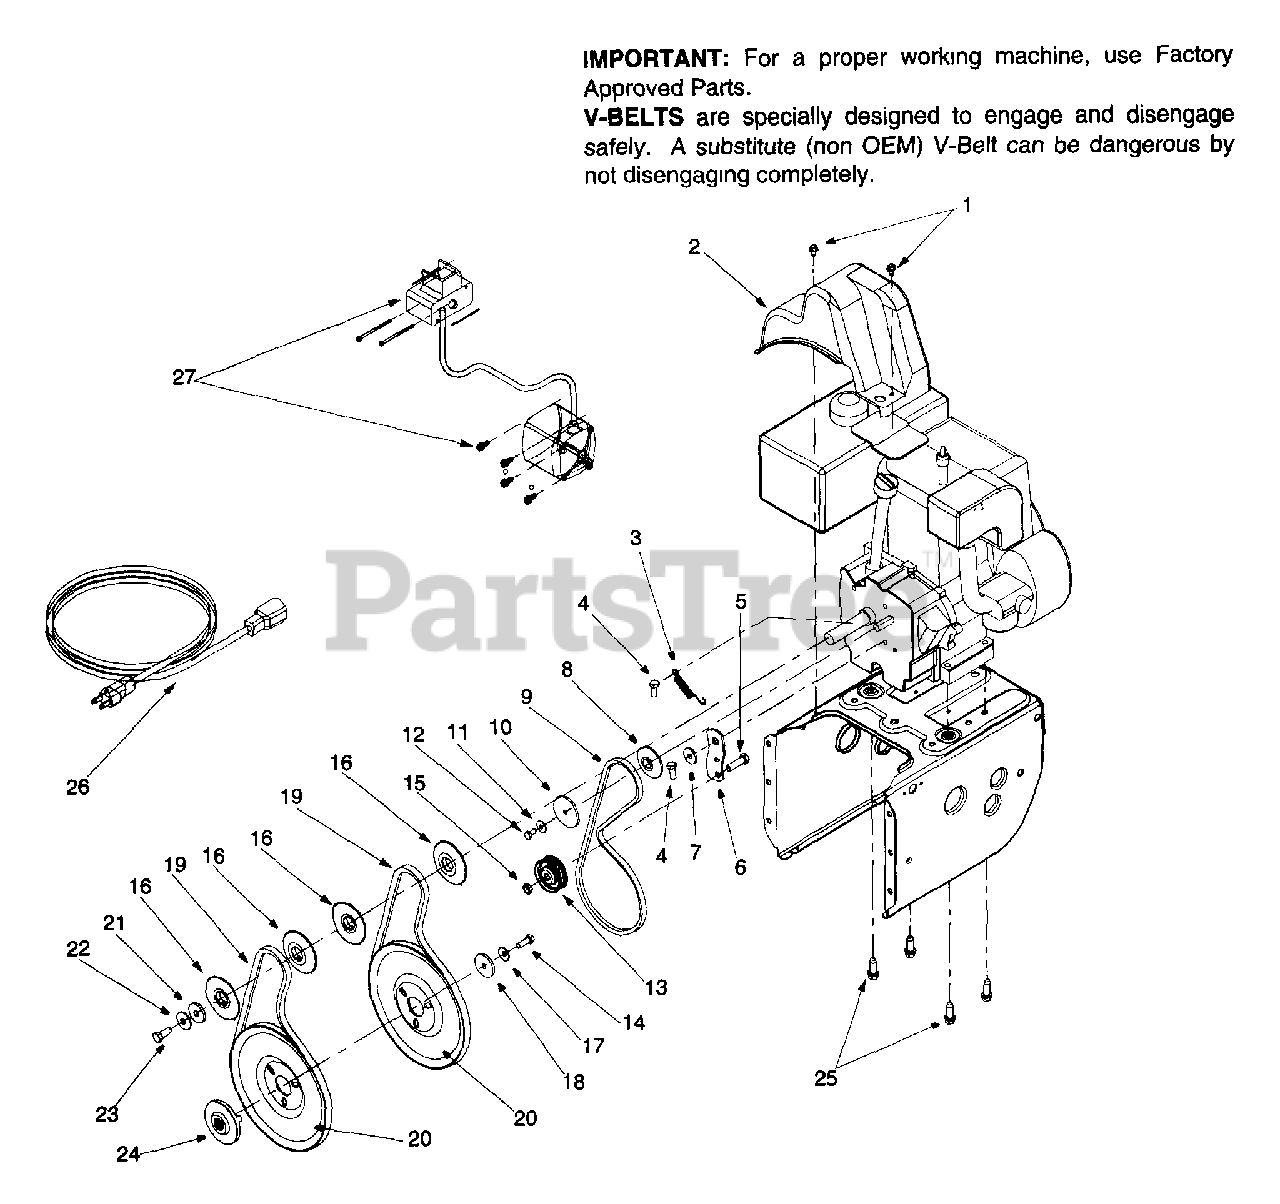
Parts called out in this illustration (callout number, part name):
1	Hex Washer Screw 1/4-20 x .50
2	Belt Cover
3	Extension Spring
4	Hex Screw 5/16-24 x .75
5	Hex Cap Screw 3/8-16 x 1.25
8	Pulley Half
9	V-Belt
10	Pulley Half
11	Bell Washer
12	Hex Cap Screw 1/4-28 x .50
13	Flat Idler
14	Lock Hex Cap Screw 5/16-24
15	Lock Jam Nut 3/8-16
16	Pulley half
17	Bell Washer
18	Flat Washer
19	Belt
20	Auger Pulley
21	Flat Washer 3/8 x 1.25 OD
22	Bell Washer
23	Hex Cap Screw 3/8-24
24	Adapter Pulley
25	Hex Screw 3/8-16 x 1.0
26	Extension Cord
27	Electric Start
